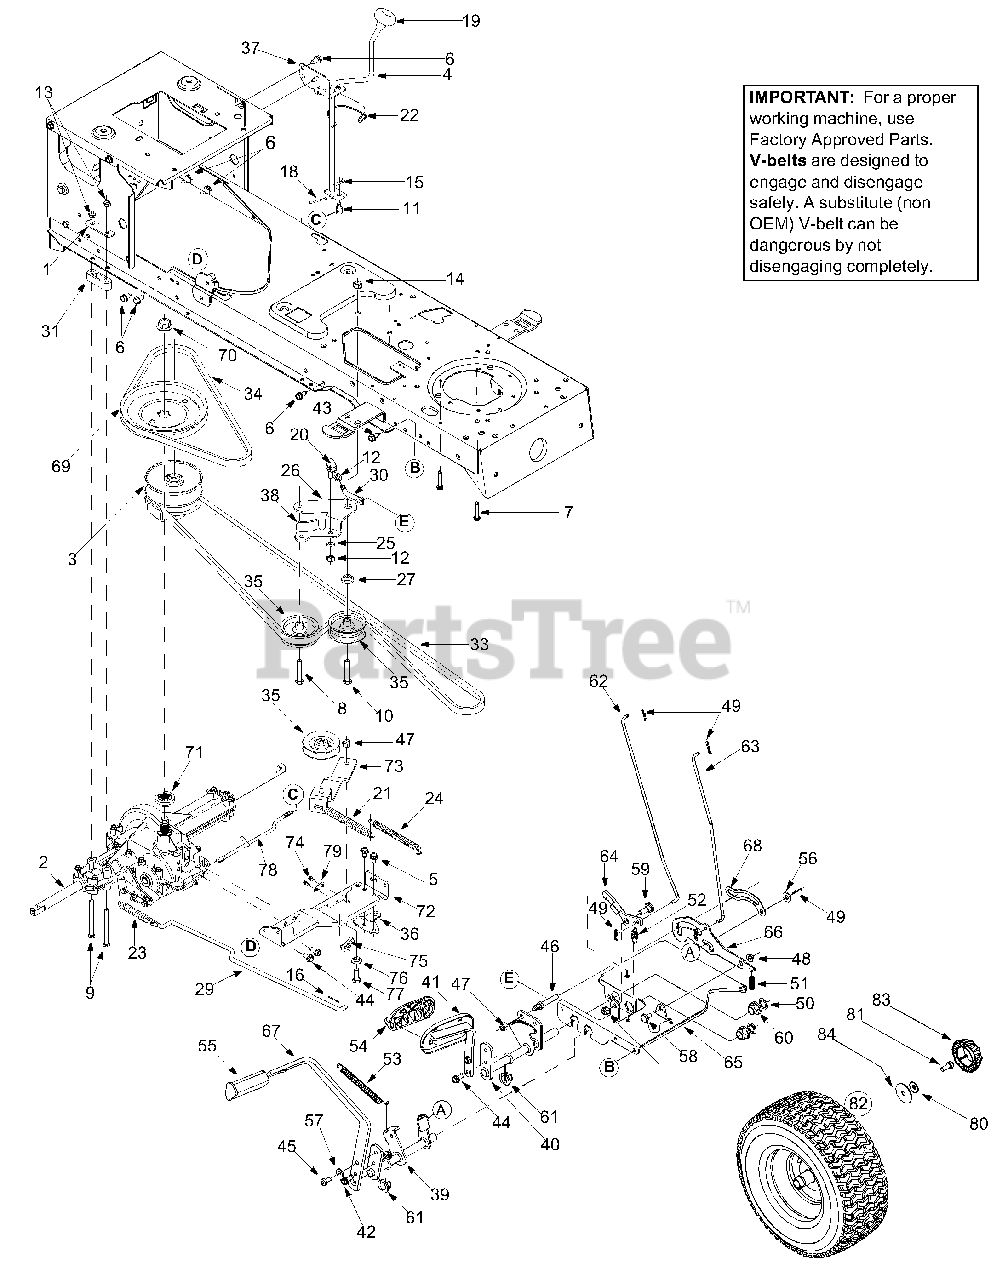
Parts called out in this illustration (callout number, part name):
1	Mounting Bracket
2	Drive Assembly
3	Variable Spd. Pulley Assembly
4	Shift Lever Assembly
5	TT Screw 5/16-18 x 0.5
6	AB Screw 5/16-12 x 0.75
7	TT Screw 1/4-20 x 1.25
8	TT Sems Screw 3/8-16 x 1.5
9	Hex Bolt 5/16-18 x 3.5
10	Hex Bolt 3/8-16 x 2.0
12	Hex Nut 3/8-24
13	Hex Lock Nut 5/16-18
14	Flange Lock Nut 3/8-16
15	Hairpin Clip
16	Cotter Pin
17	Hairpin Clip
18	Cotter Pin
19	Shift Knob
20	Ball Joint
21	Extension Spring
22	Spring Clip
23	Extension Spring
24	Extension Spring
25	Lock Washer 3/8
26	Grease
27	Shoulder Spacer
30	Idler Adj. Rod
31	Spacer: Transaxle
35	Flat Idler Pulley 2.75 OD
35	Idler V Pulley 5L X 3.062 OD
36	Shift Bracket
37	Shift Bracket
39	Brake Control Assembly
40	Speed Control Assembly
41	Drive Pedal Assembly
42	TT Screw 5/16-18 x 0.875
43	AB Screw 5/16-12 x 0.75
44	LD Screw 5/16-18 x 0.75
45	TT Screw 5/16-18 x 0.75
47	Hex Lock Nut 3/8-16
48	Flange Lock Nut
49	Cotter Pin
50	Push Nut
51	Compression Spring
52	Extension Spring
53	Extension Spring
54	Control Pad
56	Flat Washer
57	Flat Washer
58	Shoulder Screw
59	Shoulder Screw
60	Hex Flange Bearing
61	Hex Flange Bearing: Split
62	Brake Lock Rod
63	Cruise Control Rod
64	Cruise Latch
65	Steering Support Bracket
66	Lock-Out Bracket
69	Transmission Pulley
70	Flange Nut 9/16-18
71	Pulley Hub
72	Transmission Torque Bracket
73	Idler Bracket
74	AB Screw #8-18 x 0.5
75	Spring Switch
76	Shoulder Spacer
77	Hex Bolt 3/8-16 x 1.0
79	Insulator Nut Plate
80	Bell Washer
81	Hex Cap Screw
82	Air Valve
83	Hub Cap
84	Flat Washer
